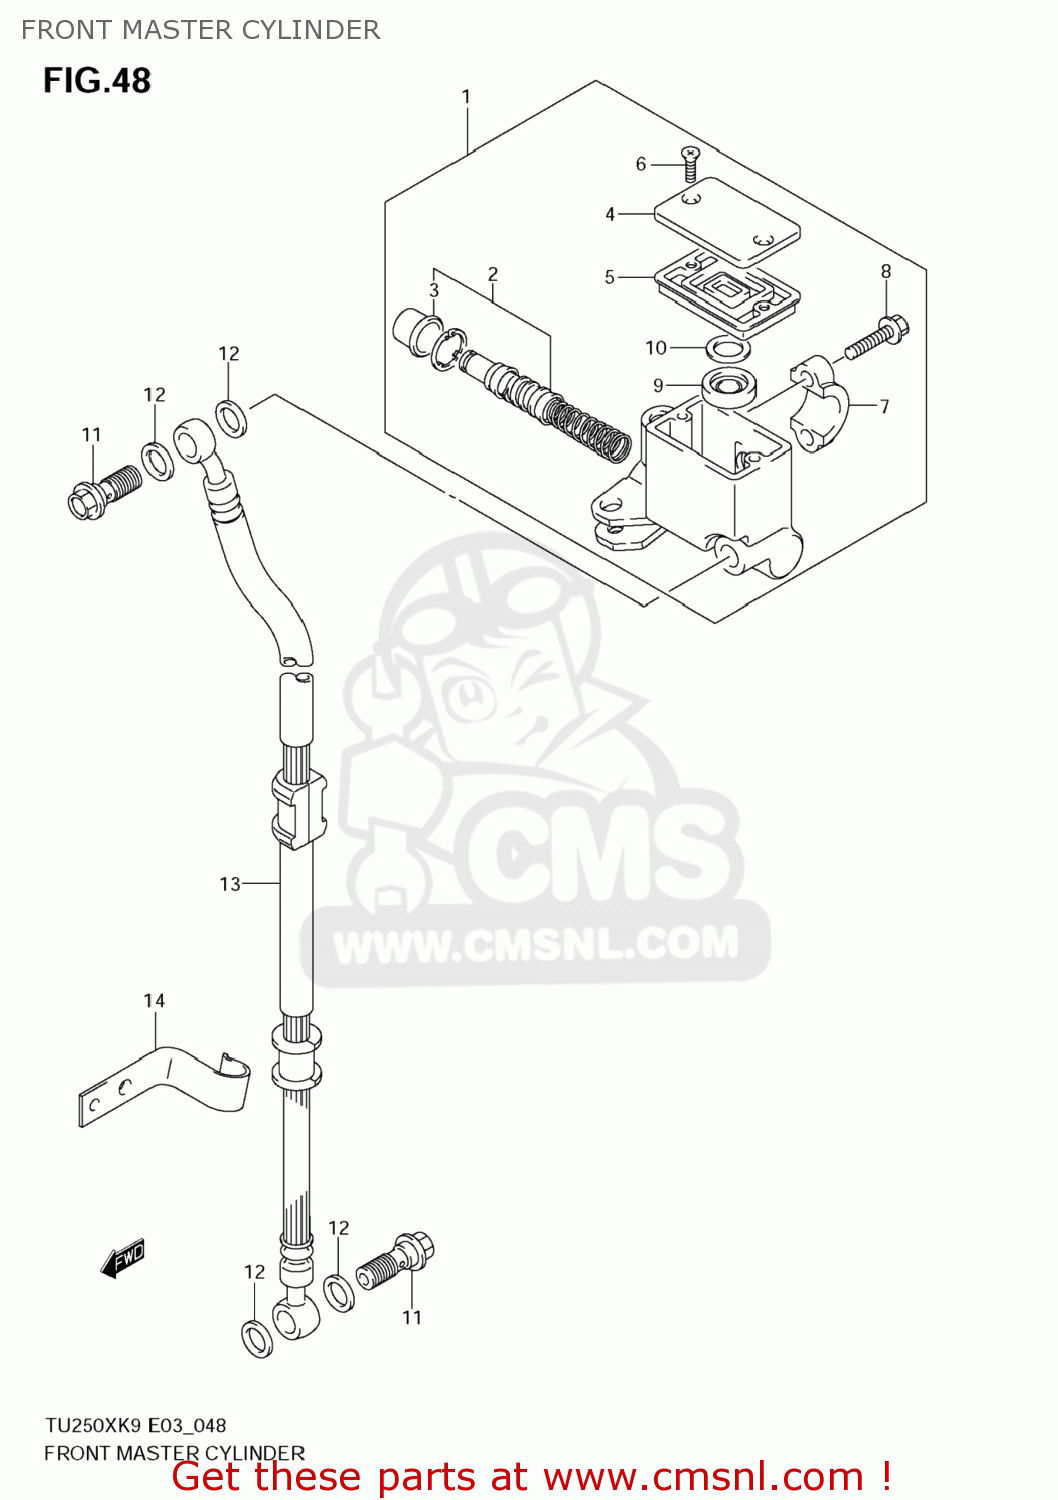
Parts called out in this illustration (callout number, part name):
1	CYLINDER ASSY,FR MASTER
2	PISTON/CUP SET
3	BOOT
4	CAP
5	DIAPHRAGM
6	SCREW
7	HOLDER
8	BOLT(6X25)
9	SEPERATOR
10	PLATE
11	BOLT UNION
12	WASHER(10X15X1.5)
13	HOSE,FR BRAKE
14	CLAMP,FR BRAKE HOSE LWR
